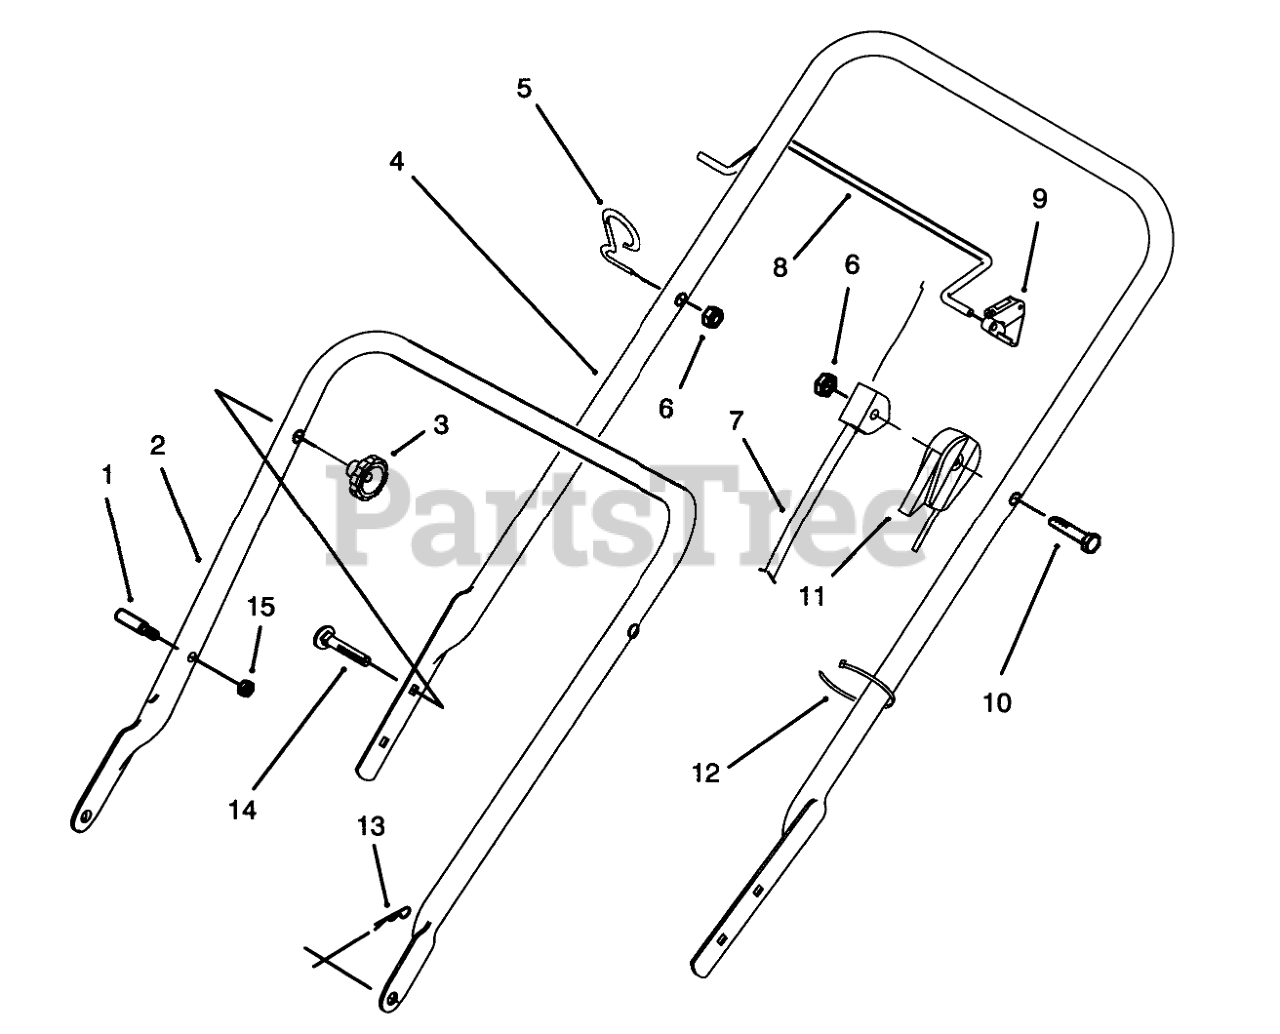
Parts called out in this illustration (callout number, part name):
1	HANDLE PIN
2	LOWER HANDLE ASM
4	UPPER HANDLE
5	GUIDE-ROPE
6	NUT-LOCK, NI
7	BRAKE CONTROL
8	Bar-Control
9	STOP-PIVOT
10	SCREW-HH
11	THROTTLE CONTROL
12	TIE-CABLE
13	PIN-COTTER, HAIR
14	SCREW
15	NUT-LOCK, NI
